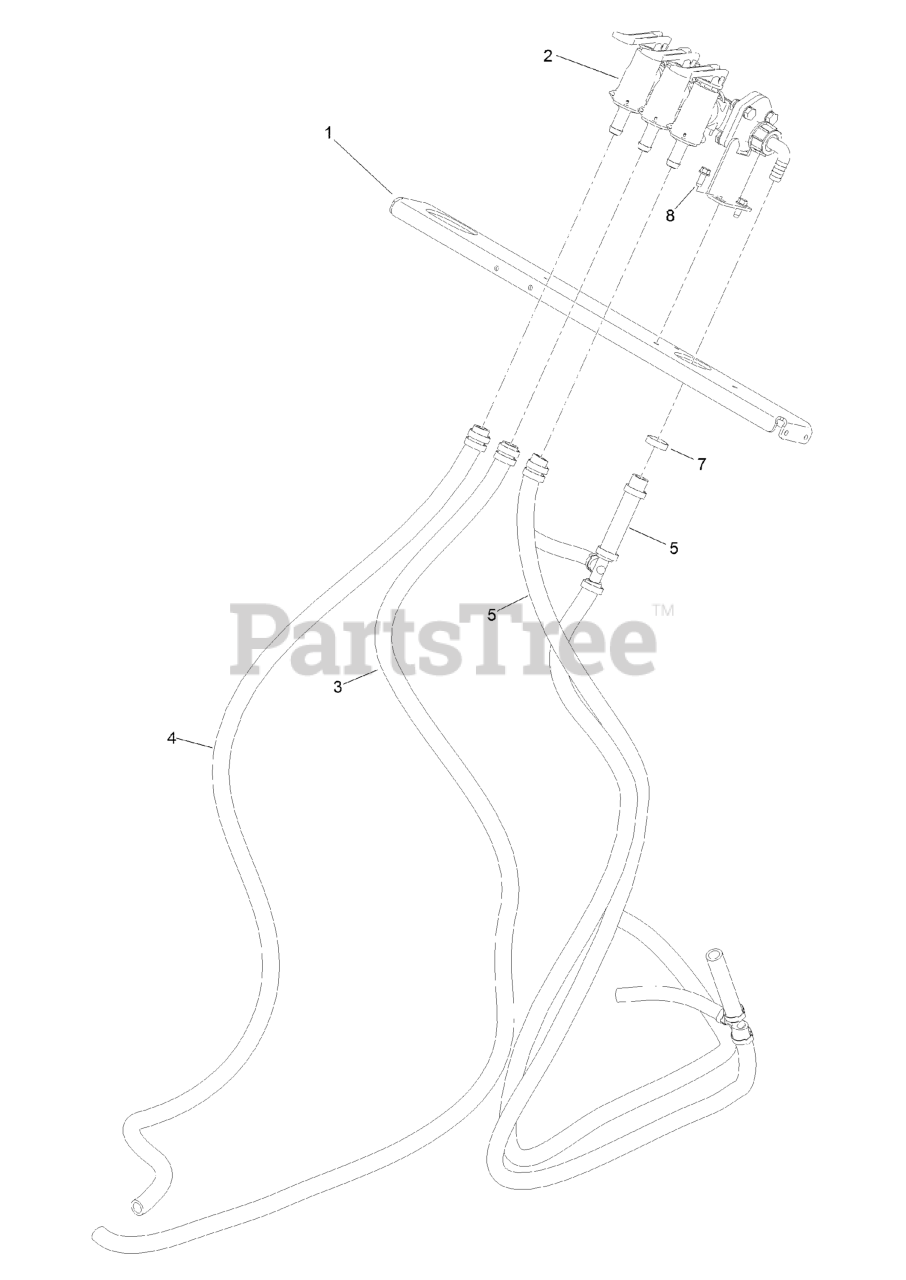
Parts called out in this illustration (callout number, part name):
1	Crossmember-Column
2	Manifold-Valve, Control
3	HOSE-WATER
4	HOSE-WATER
5	Hose ASM
7	CLAMP OETIKER 0.716"" CLOSED 0.826"" OPEN
8	SCREW-HWH
